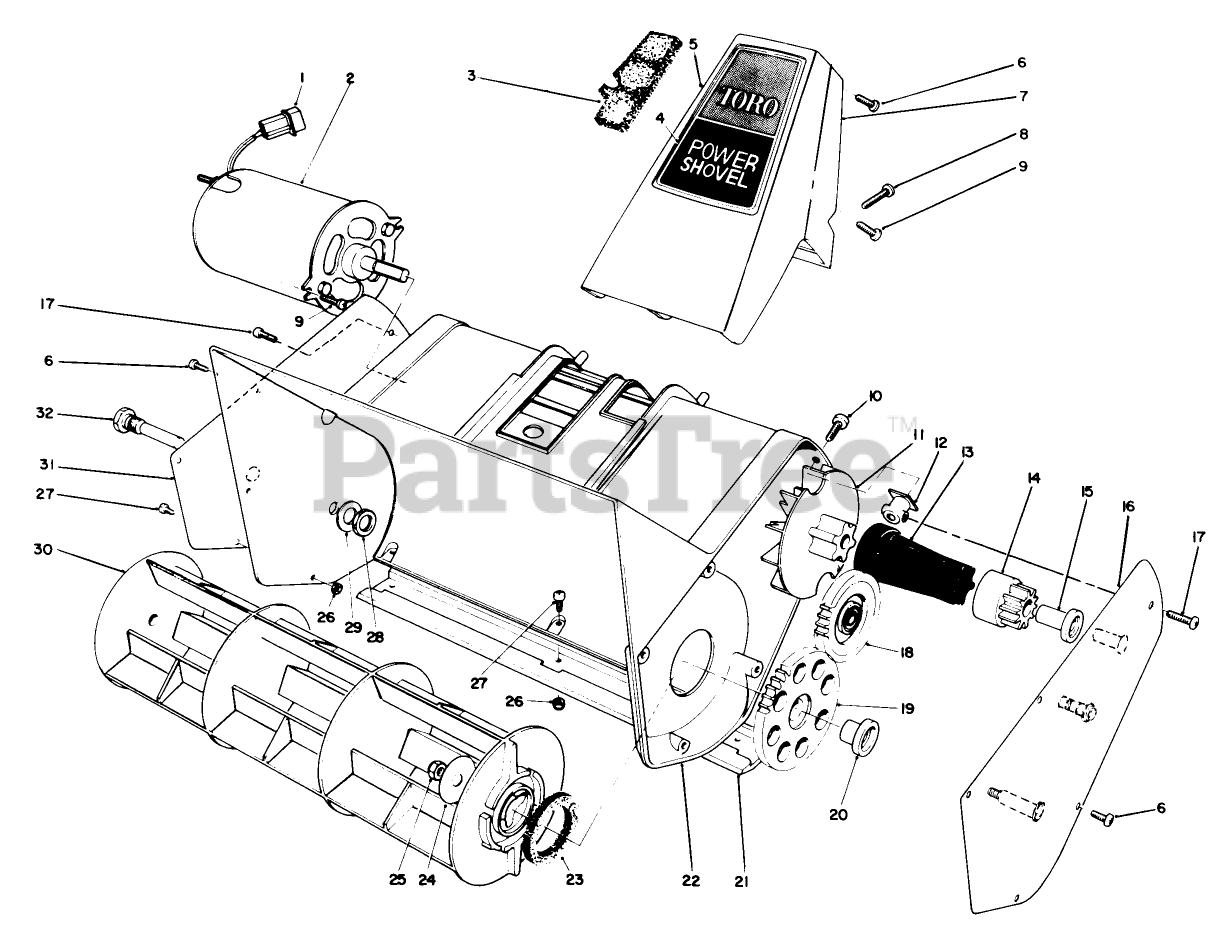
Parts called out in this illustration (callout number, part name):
3	FOAM FILTER
4	HANDLE SUPT DECAL
5	HANDLE SUPPORT, FRONT
6	SCREW-PPH
8	SCREW-PPH
9	SCREW-PPH
10	#10-10X3/4 PLASCREW
11	FAN, POWER SHOVEL
12	MOUNTING BLOCK
13	DRIVE COUPLING
14	DRIVE GEAR ASM
15	BUSHING, DRIVE GEAR
18	IDLER GEAR ASM
23	FELT WASHER
24	ROTOR WASHER
25	NUT-LOCK, NI
26	NUT-LOCK
27	SCREW-PPH
28	NUT-LOCK, CONE
29	WASHER-FLAT
30	ROTOR
31	RT. SIDE COVER (RAW)
32	ROTOR PIN
